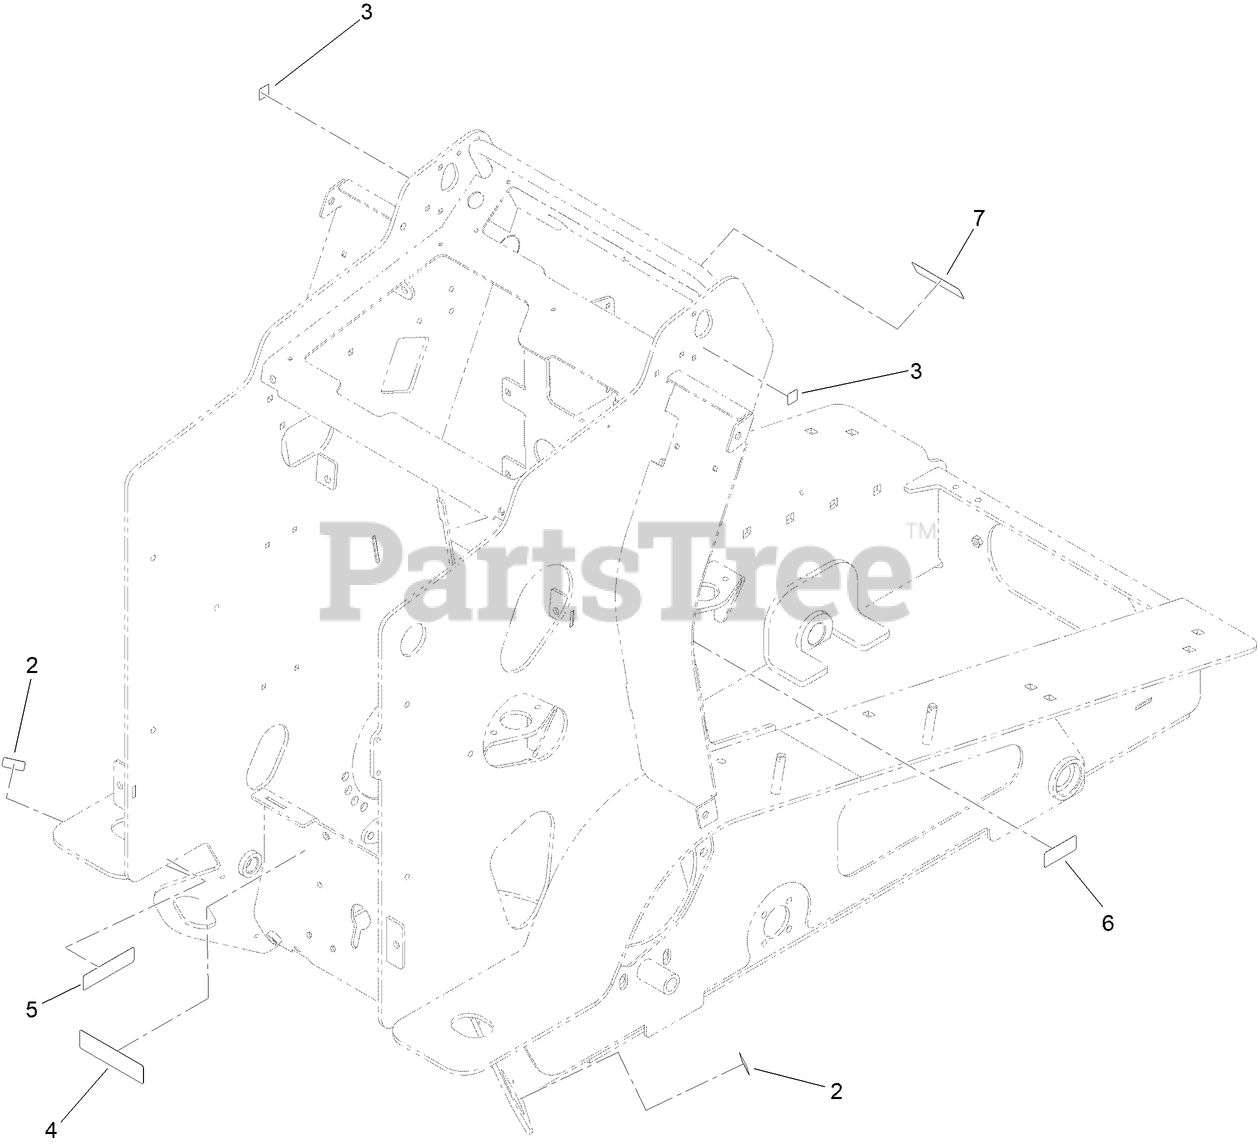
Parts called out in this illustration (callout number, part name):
2	DECAL-TIEDOWN
3	DECAL-POINT, LIFT
4	DECAL-PARKING BRAKE
5	DECAL-ARRESTOR, SPARK
6	DECAL-SURFACE, HOT
7	DECAL-RADIATOR FILL
